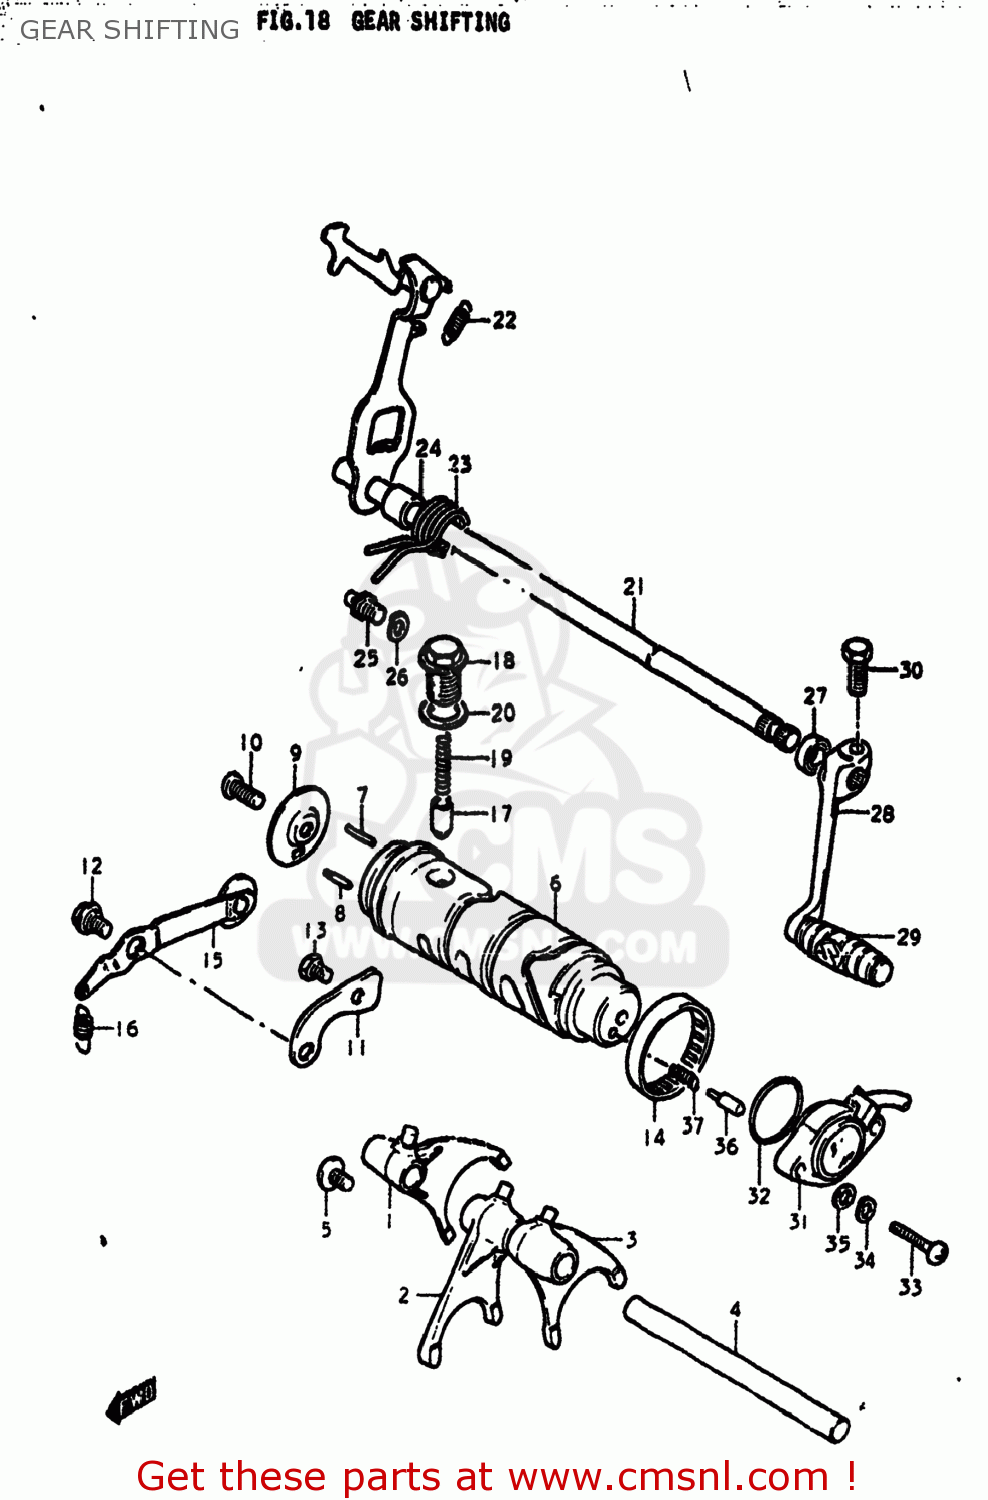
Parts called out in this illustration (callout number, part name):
1	FORK,GEAR SHIFT NO.1
2	FORK,GEAR SHIFT NO.2
3	FORK,GEAR SHIFT NO.2
4	SHAFT,GEAR SHIFT FORK
5	SCREW
6	CAM,GEAR SHIFT
7	PIN(4X18.5)
8	PIN
9	RETAINER,GEAR SHIFT CAM DR PIN
10	SCREW
11	GUIDE,GEAR SHIFTING CABLE
12	BOLT
13	BOLT
14	BEARING(40X47X12)
15	STOPPER,GEAR SHIFT CAM NO.1
16	SPRING
17	STOPPER,GEAR SHIFTING
18	BOLT,GEAR SHAFT CAM STOPPER
19	SPRING
20	GASKET(14X19.2X2) (NAS)
21	SHAFT,GEAR SHIFT
22	SPRING
23	SPRING
24	SPACER(12X20X15.3)
25	STOPPER,GEAR SHIFT CAM
26	WASHER
27	OIL SEAL
28	LEVER ASSY,GEAR SHIFT
29	RUBBER,GEAR SHIFT PEDAL
30	BOLT
31	BASE ASSEMBLY,NEUTRAL SWITCH TERMINAL
32	O-RING (D:2.4 ID:26.2)
33	SCREW 5X20
34	LOCK WASHER
35	WASHER
36	PIN(5X15.5)
37	SPRING
